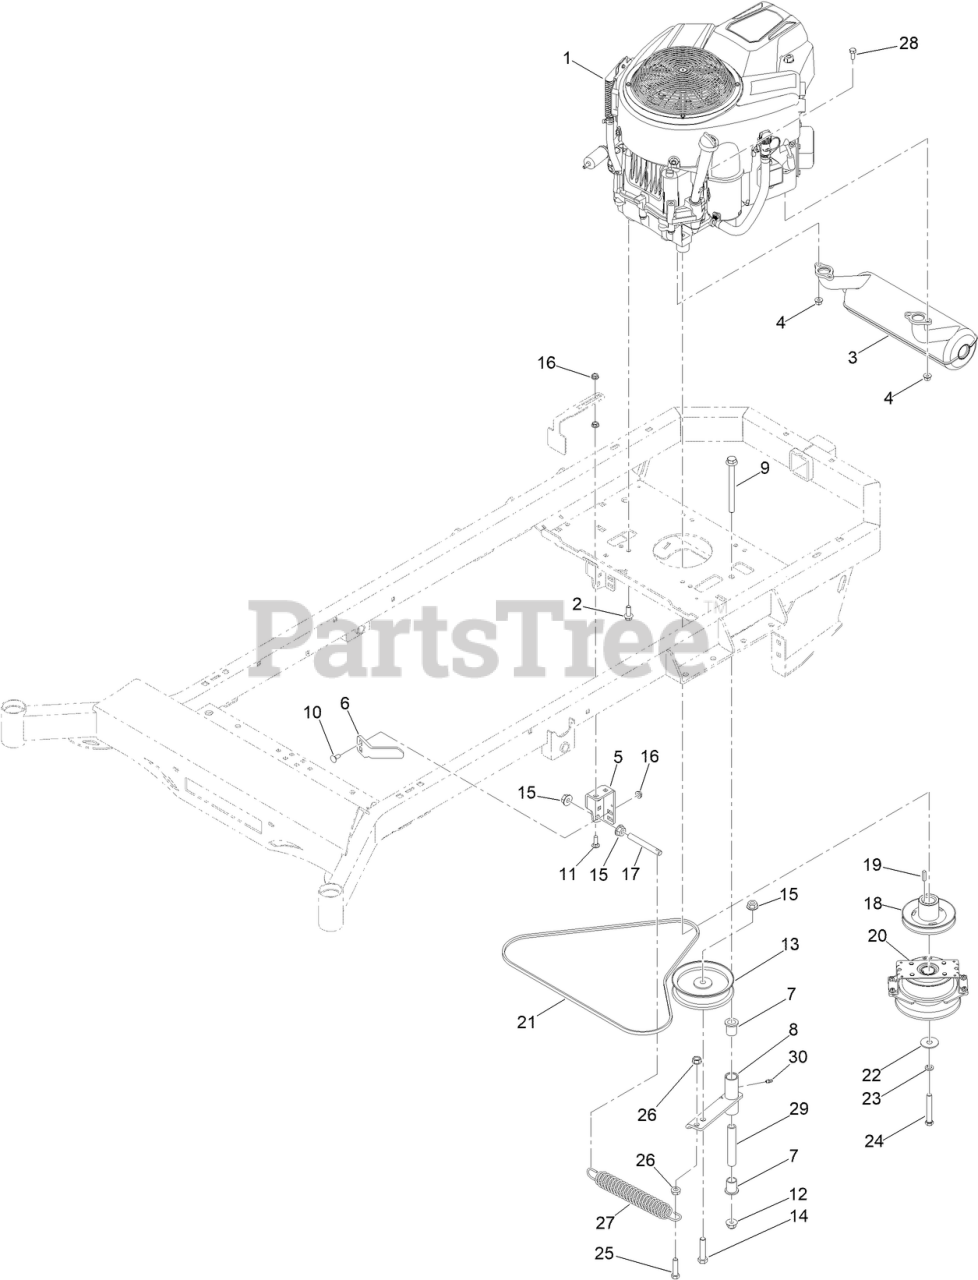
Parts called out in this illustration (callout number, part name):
1	27HP BRIGGS CXI ENGINE
2	3/8-16 X 1-1/8 IND HWH W/SERR TRI LOB ZY
3	EXHAUST SYST BRIGGS 25/ 27HP ENGNS
4	NUT-HF
5	MWR PUMP IDLER TENSIONING BRKT BLACK
6	2021 TTQ MOWER OGURA CLUTCH BRACKET
7	3/4IN ID X15/16IN OD X 1-1/8IN FLNG BUSH
8	MWR PUMP IDLER ASSY BLACK
9	1/2-13 X 5-1/2 HEX FLANGE BOLT GR 8 ZY
10	BOLT-CARR
11	BOLT-CARR
12	NUT-LOCK
13	5-3/4IN IDLER PULLEY 7/16IN SPACER ASSY
14	SCREW-HH
15	NUT-HHF
17	MWR PUMP IDLER SPRING TENSIONER
18	MWR HYDRAULIC PUMP DRIVE PULLEYA BELT
20	MWR TTQ OGURA CLUTCH
21	MWR PUMP BELT RT A X 68.25IN EFF LNGTH
22	1/2IN X 1-5/8 BELLEVILLE CUP WASHER YZ
23	WASHER-LOCK
24	TTQ CLUTCH BOLT
26	NUT-HF
27	MWR DECK SPRING
28	M8-1.25 X 20MM HEX FLANGE BOLT ZINC 10.9
29	MWR INNER IDLER SPACER
30	1/4IN DRIVE TYPE GREASE FITTING YZ
